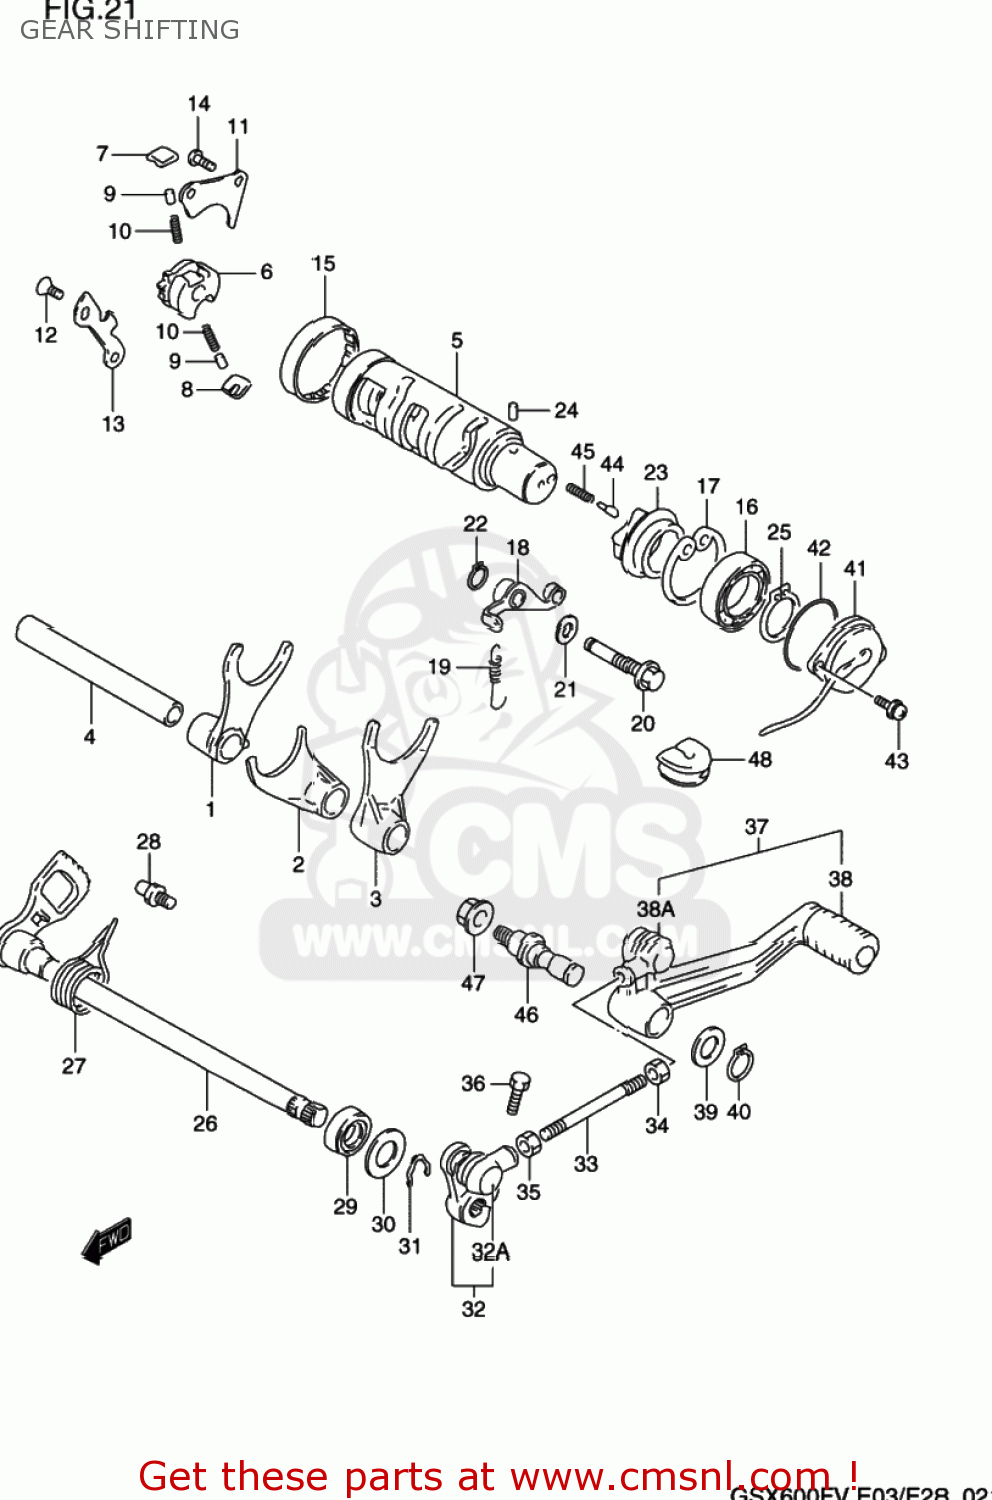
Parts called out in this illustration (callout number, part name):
1	FORK,GEAR SHIFT NO.1
2	FORK,GEAR SHIFT NO.2
3	FORK,GEAR SHIFT NO.3
4	SHAFT,GEAR SHIFT FORK(L:128)
5	CAM,GEAR SHIFT
6	GEAR,GEARSHIFT CAM DRIVE
7	PAWL,GEAR SHIFT NO.1
8	PAWL,GEAR SHIFT NO.2
9	PIN(5X8)
10	SPRING
11	LIFTER,GEAR SHIFT PAWL
12	SCREW
13	GUIDE,GEAR SHIFT CAM
14	SCREW
15	BEARING(43X49X12)
16	BEARING
17	CIRCLIP
18	STOPPER,GEAR SHIFT CAM
19	SPRING
20	SHAFT,GEAR SHIFT CAM STOPPER
21	GASKET(10X14X3.6) (NAS)
22	CIRCLIP
23	PLATE,STOPPER
24	PIN
25	CIRCLIP
26	SHAFT,GEAR SHIFT
27	SPRING
28	STOPPER,GEAR SHIFT CAM
29	OIL SEAL
30	WASHER (12.5X27X1.6)
31	CIRCLIP,12 MM
32	ARM,GEAR SHIFT LINK
32A	COVER,DUST
33	ROD,GEAR SHIFT LINK
34	NUT
35	NUT
36	BOLT
37	LEVER ASSY,GEAR SHIFT
38	RUBBER,GEAR SHIFT PEDAL
38A	COVER,DUST
39	WASHER(12.5X20X1)
40	CIRCLIP,12 MM
41	TERMINAL BASE ASSY,NEUTRAL
42	O RING(D:2.4,ID:35.5)
43	SCREW
44	PIN(5X15.5)
45	SPRING
46	SHAFT,GEAR SHIFT LEVER
47	NUT
48	GROMMET,LEADWIRE
